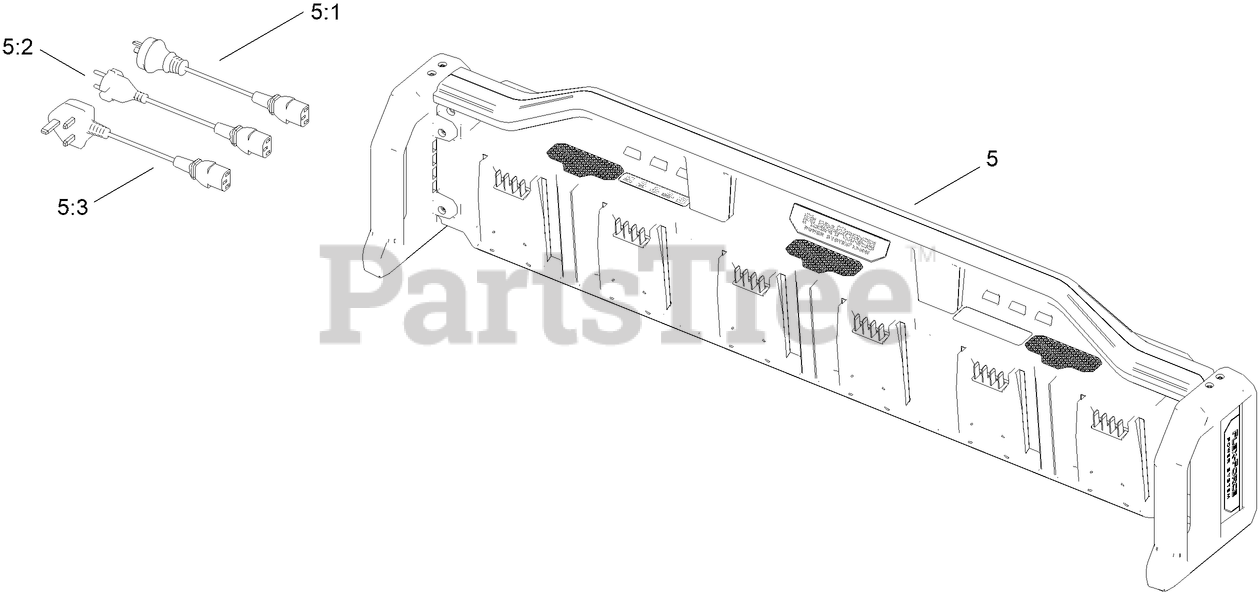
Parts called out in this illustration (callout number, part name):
5	CHARGER-BATTERY, SIX POD 60V 12 AMP CE
5:1	CORD-CHARGER, SIX POD, AU/NZ
5:2	CORD-CHARGER, SIX POD, CE
5:3	CORD-CHARGER, SIX POD, UK
